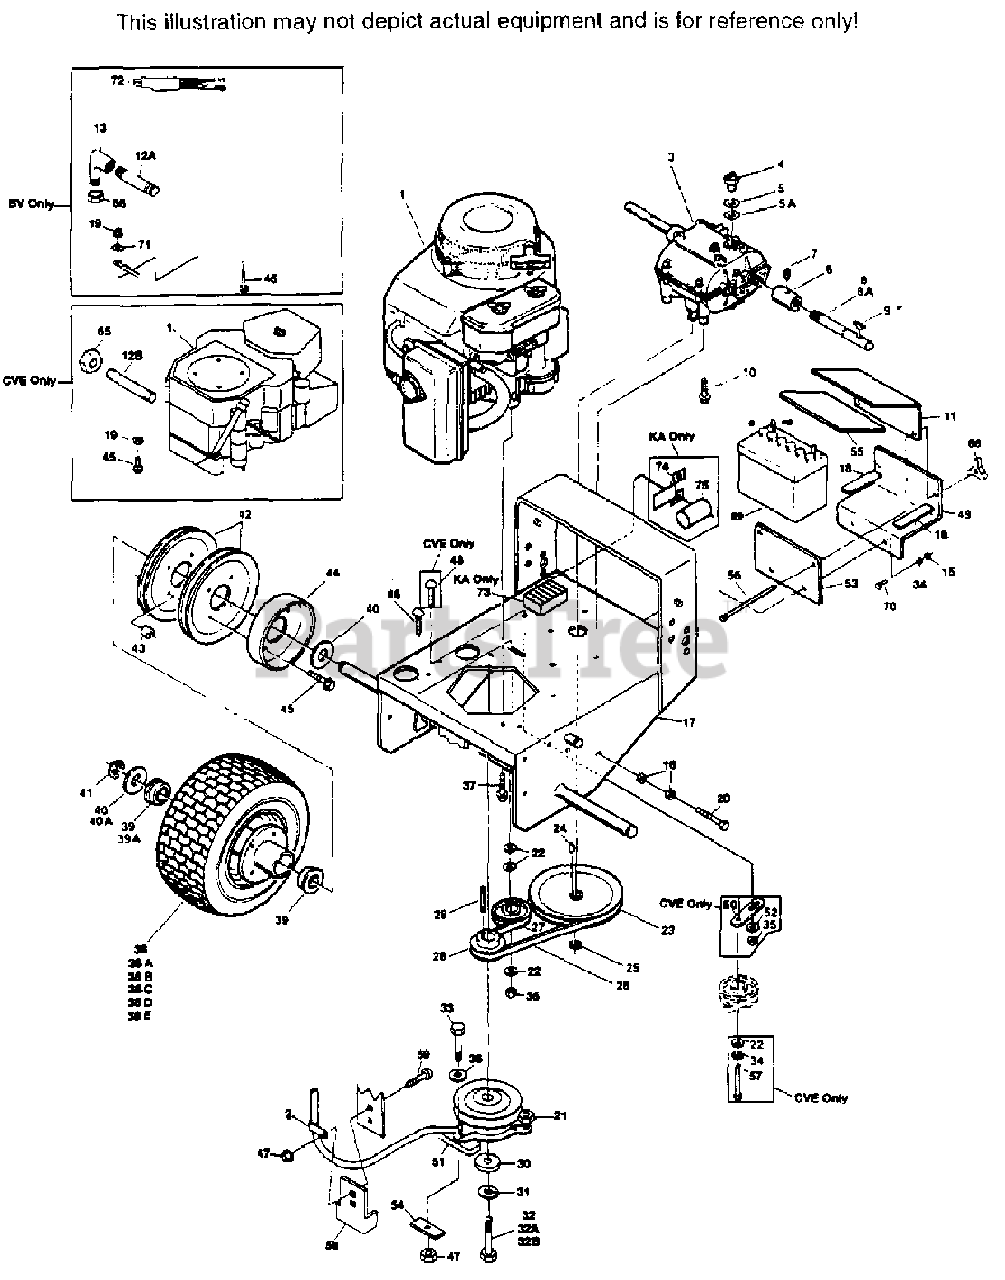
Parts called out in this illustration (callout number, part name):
2	CABLE CLAMP
3	TRANSMISSION, 5-SPEED(PEERLESS 700-026)
4	NEUTRAL SAFETY SWITCH
5	FIBRE WASHER, THIN
5A	FIBRE WASHER, THICK
6	COUPLER, JACKSHAFT
7	GREASE FITTING, STRAIGHT 1/4-28
8A	JACKSHAFT(FITS SW52, 61, & 72)
9	KEY, HI-PRO #9
10	CAPSCREW, 5/16-18 X 3/4", SERRATED FLANGE
16	NUT, 3/8-16 SERRATED FLANGE
17B	ENGINE DECK(FITS SW52, 61, 72)
21	ELECTRIC CLUTCH
22	WASHER, 25/64 X 15/16 X 12 GA.
23	PULLEY, TRANSMISSION INPUT
24	KEY, WOODRUFF #9
25	RETAINING RING, 5/8 EXT. BASIC
26	BELT, TRANSMISSION DRIVE
27	IDLER PULLEY, TRANSMISSION
28	PULLEY, TRACTION DRIVE
29	KEY, 1/4 X 1/4 X 3/4"
30	FLAT WASHER, 7/16 SPECIAL
31	LOCK WASHER, 7/16"
35	ELASTIC STOP NUT, 3/8-16
38	WHEEL ASSEMBLY(INCL. 38A-38B)(FITS SW36,
38A	TIRE, 13 X 6.50-6, 2-PLY(FITS SW36, 48, 52,
38B	RIM & BEARING ASSEMBLY(INCL. 39)(FITS
39	WHEEL BEARING NWC(OD 1.984-1.980)
39	WHEEL BEARING(OD 2.000-2.005)
40	WASHER, 1-1/16 X 1-3/4 X 12 GA.
40A	WASHER, 1-1/16 X 1-1/2 X 18 GA.
41	RETAINING RING, 1" EXT.-"E"
42	PULLEY, WHEEL DRIVE
43	SPACER, WHEEL PULLEY
44	BRAKE DRUM
46	SHORT SQUARE NECK CARRIAGE BOLT, 3/8-16 X 2"
47	HEX NUT, 5/16-18 ELASTIC STOP
51	RUBBER PAD, CLUTCH STOP
54	BACKING PLATE
58	ANTI ROTATION BRACKET
